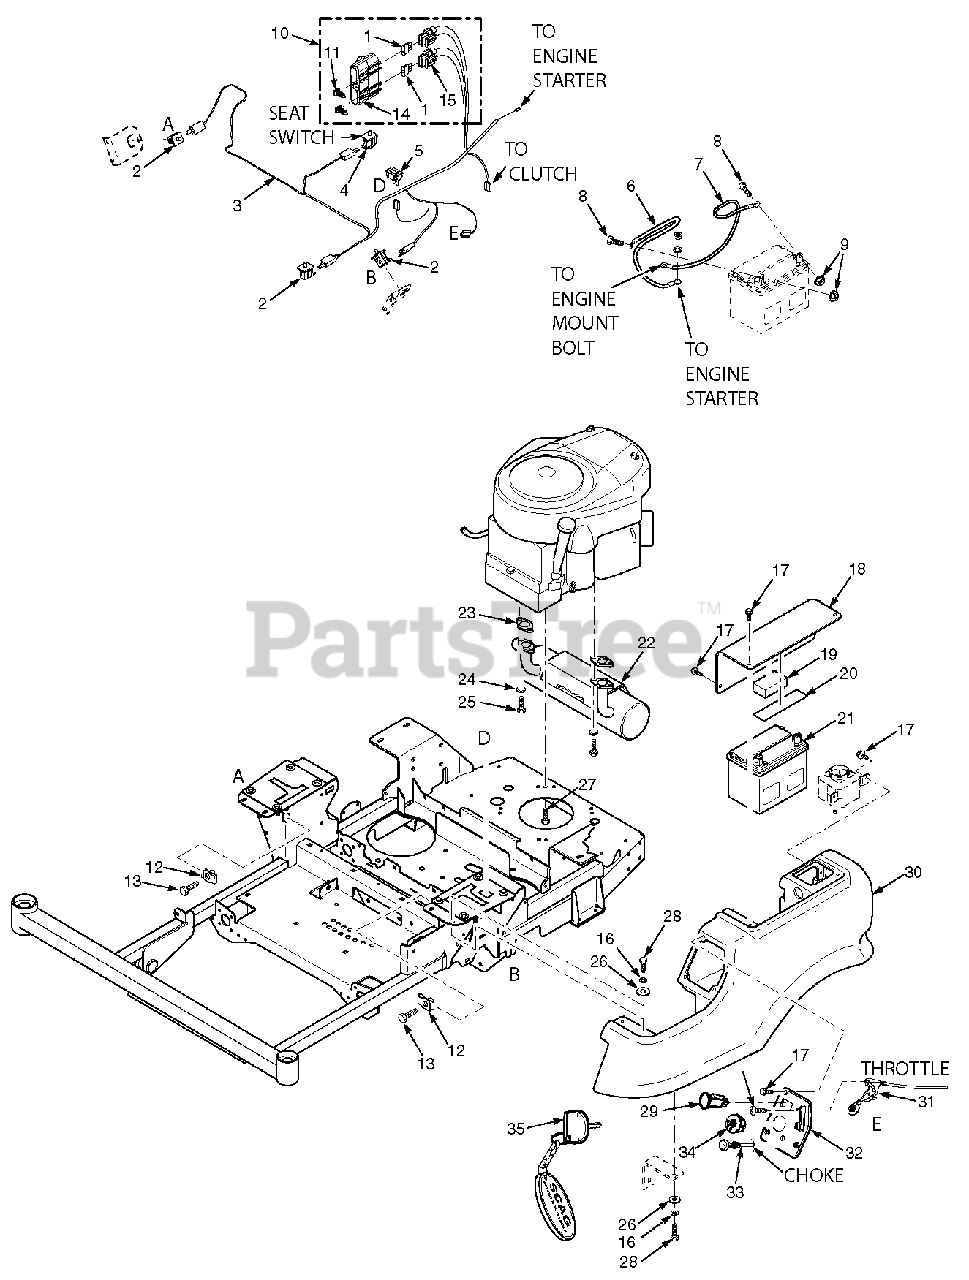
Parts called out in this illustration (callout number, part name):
1	Fuse, 20 amp
2	Switch
3	Wire Harness, Main
4	Switch, Seat
5	Hourmeter
6	Battery Cable, Red 25"
7	Battery Cable, Black 27"
8	Bolt, Hex Head 1/4-20 x 1/2"
9	Nut, 1/4-20
10	Double Fuse Assy.
11	Clip, Wire
12	U-Nut, 3/8-16
13	Bolt, Hex Head 3/8-16 x 1-1/4" Special Lock
14	Cover, Sealed Double
15	Fuse Holder
16	Lockwasher, 5/16" Spring
17	Bolt, Hex Head 1/4-20 x 1/2" Serr. Flange
18	Battery Cover
19	Pad, Battery Hold Down
20	Rubber Pad
21	Battery (not avail. through Scag)
22	Muffler
23	Exhaust Gasket
24	Lockwasher
25	Bolt
26	Flatwasher, 5/16-.375 x .875 x .083
27	Bolt, Hex Head 3/8-16 x 1-1/4"
27	Lockwasher, 3/8" Spring
28	Bolt, Hex Head 5/16-18 x 3/4"
29	PTO Switch
30	Tank, LH - SPZ
31	Throttle Cable
32	Instrument Panel w/Decal
33	Choke Cable
34	Ignition Switch
35	Key w/Shroud
35	Key Assembly w/Fob
